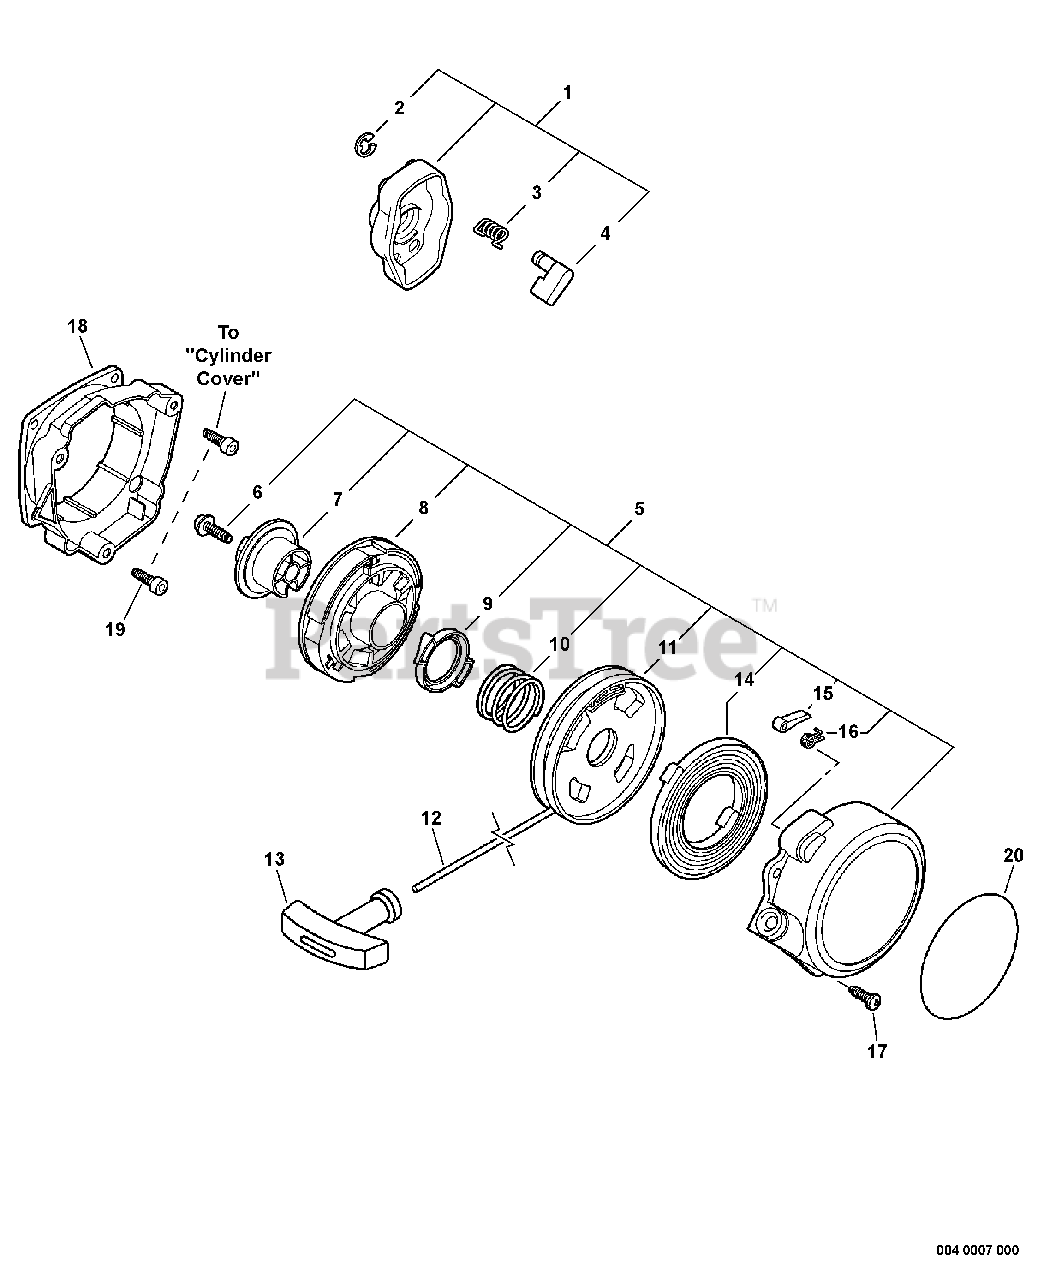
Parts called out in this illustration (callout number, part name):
1	STARTER PAWL ASSY
2	RING, RETAINING - 4
3	SPRING, RETURN
4	PAWL, STARTER
5	STARTER ASSY
7	PLATE, CAM
8	SPRING ASSY
10	SPRING, RETURN
11	REEL, ROPE
12	ROPE, STARTER - 3X800
13	GRIP, STARTER
14	SPRING, REWIND
15	PAWL, STARTER
16	SPRING, PAWL RETURN
17	SCREW - 5X20 -- TAPPING
19	SCREW - 4X16
20	LABEL - ECHO -- i
